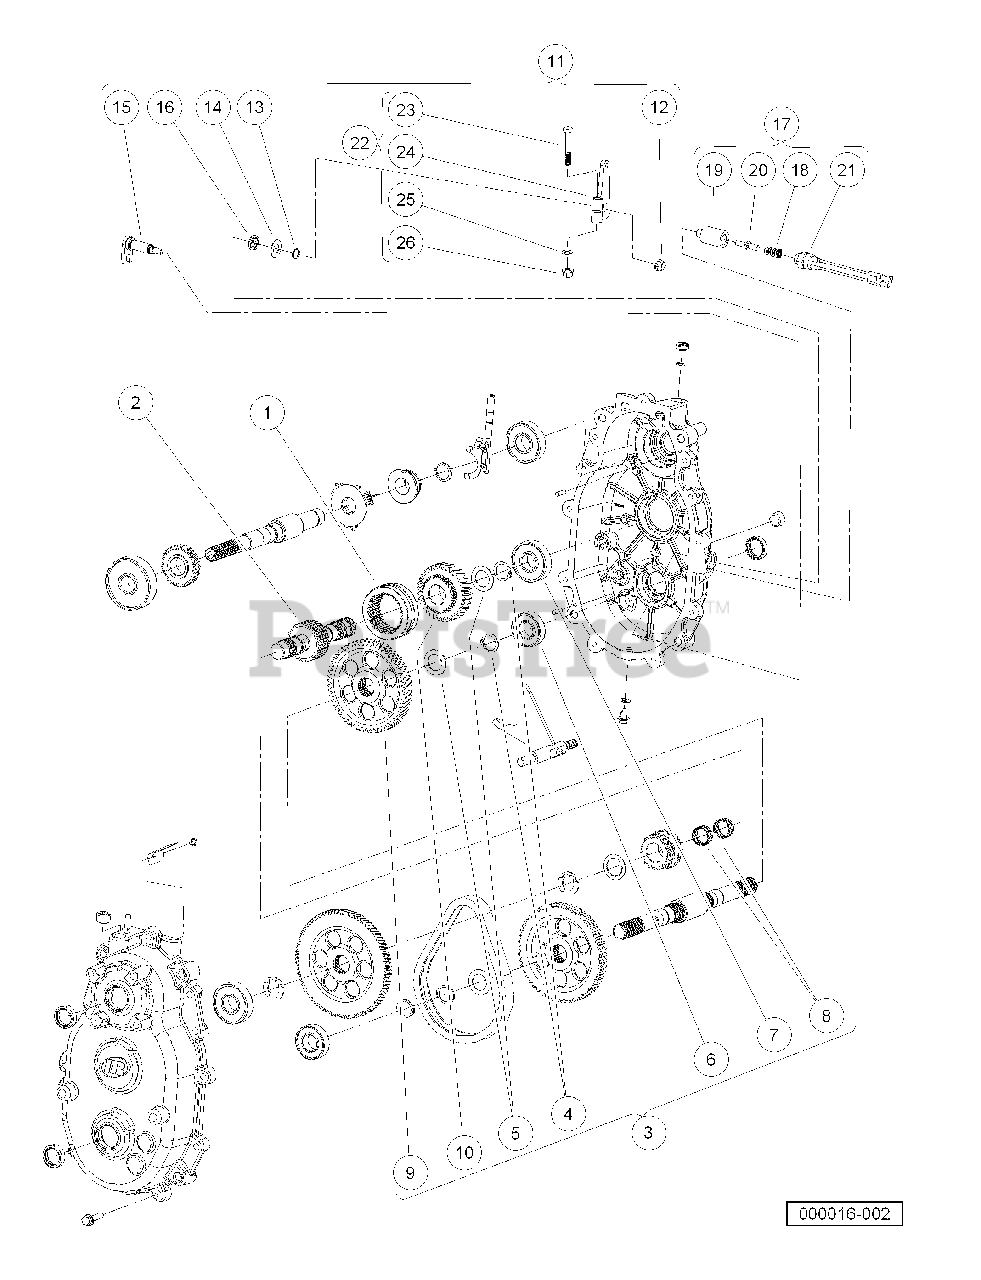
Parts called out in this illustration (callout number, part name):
1	Dog, Engagement
2	Shaft, Intermediate
3	Kit, Forward Gear Repair
4	Ring, Retaining, Basic External
5	Washer, Thrust, 1.007 X .062
6	Bearing, Ball
7	Bearing, Ball
8	Bearing, Needle
11	Kit, Trans Shift Shaft Repair
12	Nut, Lock Hex, Nylon, 5/16-24
13	Ring, Retaining, External 9/16
14	Washer, Flat, .58 X 1.08 X .05
15	Weldment, Shift, Shaft
17	Kit, Neutral Switch Repair
19	Guide, Detent Bullet
20	Bullet, Detent
21	Switch, Indicator, Pollak
22	Kit, Bellcrank, D Shape, Clamp
23	Bolt, 3/8-16 X 2.00 Hex Head
24	Asm, Bellcrank, D Shape, Clamp
25	Washer, 3/8 Type A Flat
26	Locknut, 3/8-16 Hex
